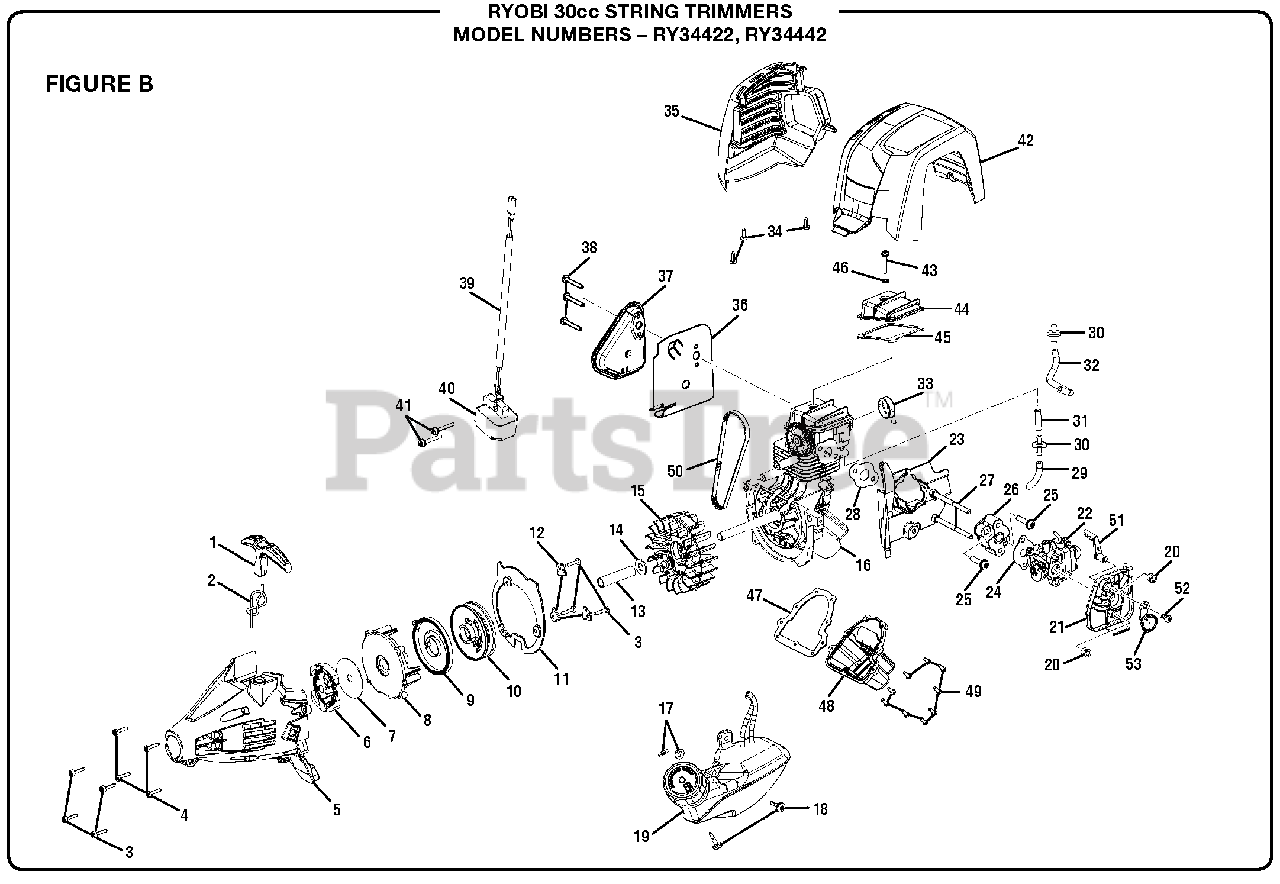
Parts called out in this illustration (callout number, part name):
1	Starter Grip
2	Starter Rope (42 in)
3	Screw (M4 x 18 mm)
4	Screw (M4 x 16 mm)
5	Starter Housing Assembly
6	Clutch Assembly
8	Starter Baffle
9	Spring & Container
10	Starter Pulley
12	Pulley Retainer
13	Spacer Tube
14	Washer
15	Flywheel Assembly
16	Short Block Assembly
18	Screw (M4)
19	Fuel Tank & Cap Assembly
20	Hex Nut (M5 x 0.8)
21	Air Filter Base
22	Carburetor Assembly
23	Air Baffle
24	Carburetor Gasket
25	Screw (M5 x 23 mm)
27	Bolt (M5 x 63 mm)
28	Heat Dam Gasket
29	Breather Hose
30	Check Valve
31	Breather Hose
32	Breather Hose
33	Breather Fitting
34	Screw (M4 x 12 mm)
35	Muffler Housing
36	Muffler Gasket
37	Muffler Assembly
38	Muffler Bolt (M5 x 42 mm)
39	Electrical Lead Wire Assembly
40	Ignition Module
41	Screw (M4 x 19 mm)
42	Top Cover
43	Screw (M4 x 27 mm Total, w/14 mm Threaded)
44	Cam Cover
49	Screw (M4 x 12 mm)
50	Timing Belt
51	Choke Lever
52	Screw (M4 x 12 mm)
53	Choke Plate
